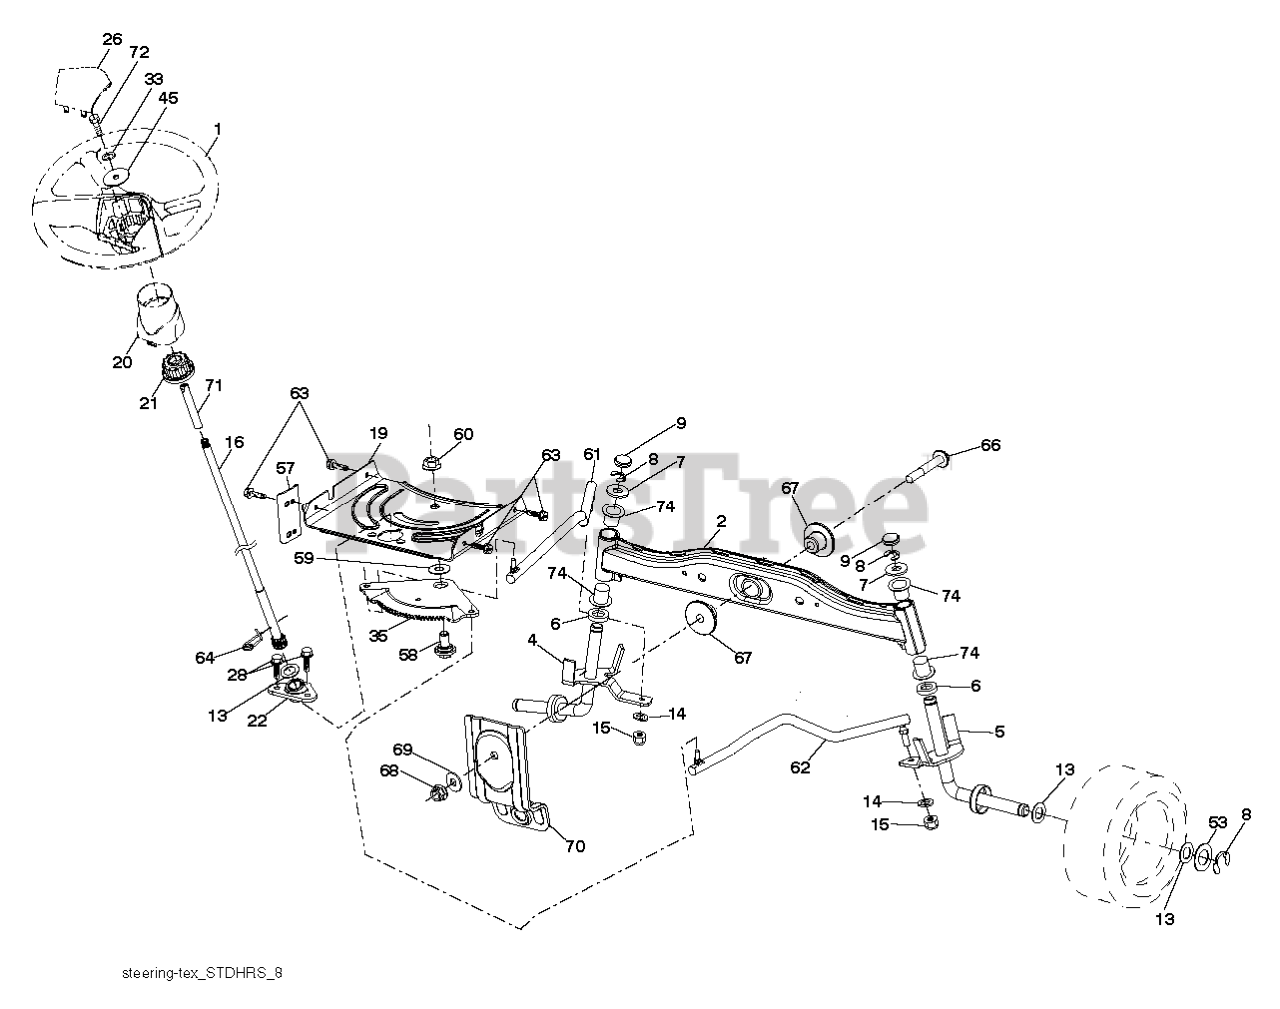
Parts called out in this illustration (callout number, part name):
1	RP WHEEL.STEER.HUSQ.PREM.OVMLD
2	AXLE HALF ASM-WELDED
4	SPINDLE.STEERING.ASM.LH.13".TI
5	SPINDLE.STEERING.ASM.RH.13".TI
6	THRUST WASHER
9	CAP.SPINDLE.BLACK
14	WASHER, LOCK 3/8
15	NUT CROWNLOCK 3/8-24
16	SHAFT.STEER.3/4.PLATED.TEX
19	PLATE.STEER.DDL.NLT/NG
20	BOOT, STEERING
21	ADAPTER, WHEEL STNG..
22	STEERING.SUPT.LOWER.
26	RP INSERT.CAP.WHL.STRG.HUSQ.
28	SCREW, 3/8-16X3/4
33	WASHER.LOCK.HVY.HLCL.SPR.5/16
35	GEAR.SECTOR.PLATE.DDL.
45	WASHER.11/32
53	WASHER.HARDENED
57	BRACKET.UPSTOP.TEX
58	BOLT.SHOULDER.SECTOR.P
59	WASHER.THURST.SECTOR.S
60	NUT FLANGE LOCK 5/8-11
61	DRAGLINK.LH.BALLSTUD.D
62	DRAGLINK.RH.BALLSTUD.D
63	SCREW
64	RETAINER.CLIP.SPRING.S
66	BOLT HEX FGHD 7/16-14 X 3 SERR
67	BUSHING.PM.FRONT AXLE
68	NUT.LOCK.FLANGE.7/16
69	WASHER.1.5X.505X.118
70	BRACKET.SUSP.MWR.FRT.30"SRD
71	SHAFT.EXTEN.STRG.SPLINE
72	BOLT 5/16-18 X 4 W/PATCH
74	BRNG T
